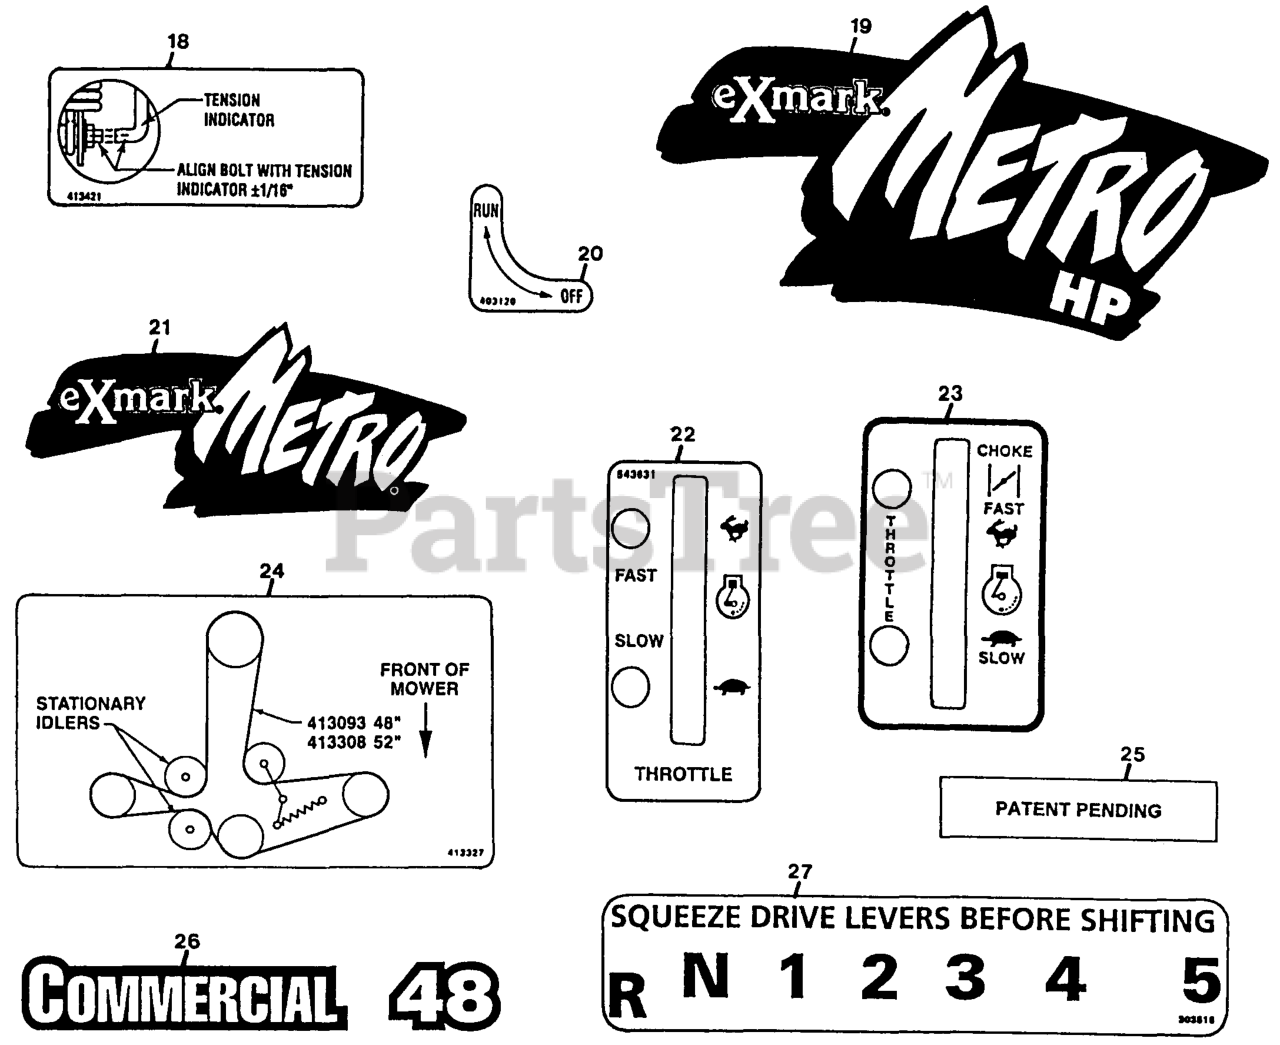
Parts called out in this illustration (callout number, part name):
18	DECAL,INDICATOR
24	DECAL,BELT ROUTING
25	Decal, Patent Pending
26	DECAL,COMMERCIAL 48
27	DECAL,SHIFTER
